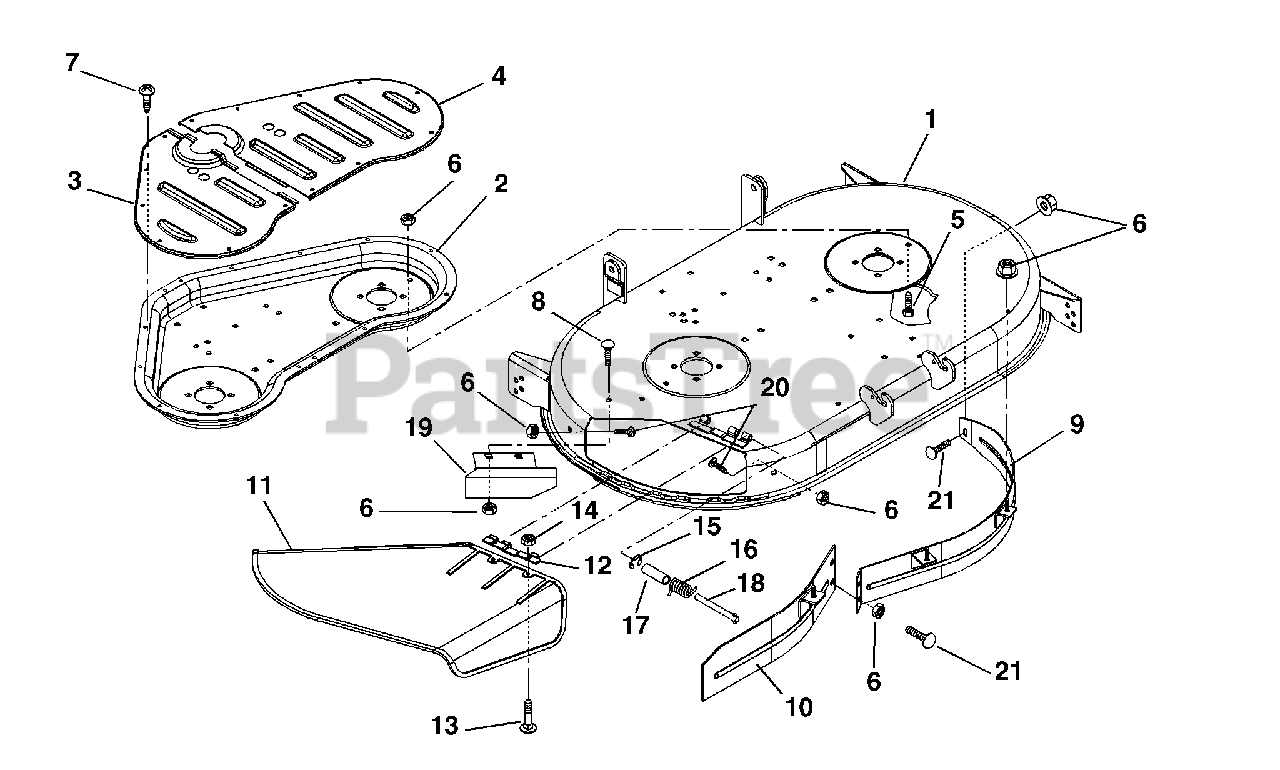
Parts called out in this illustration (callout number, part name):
1	MOWER - 42" YT W/DECALS
2	REINFORCEMENT, DECK
3	COVER, PLATE 3 RIBS
4	COVER, PLATE 5 RIBS
5	@BLT-HEX .38-16X.75 GR5 YWZC
6	@NUT-LK-TOP-FLG .38-16 YWZC
7	@SCR-TAP .31-18X.50 HWH TR YWZ
8	@BLT-HEX .38-16X.75 GR5 YWZC
9	WELDMENT, BAFFLE UPPER LH
10	WELDMENT, BAFFLE UPPER RH
11	DEFLECTOR, CHUTE
12	HINGE PLATE
13	@BLT-RDHDSQNK .25-20X.75 G5YZ
14	@NUT-SPNLK-FLG .25-20 YWZC
15	RG-RTNG-EXT .312X.025
16	SG-TORS .095X.50X 1.0
17	BSHG-SLV .334 X .502 X 1.437
19	DEFLECTOR (BAFFLE)
20	BLT-RDHDSQSHK.31-18X.75 GR2 YW
21	@BLT-RDHDSQNK .31-18X.75 G5YZ
